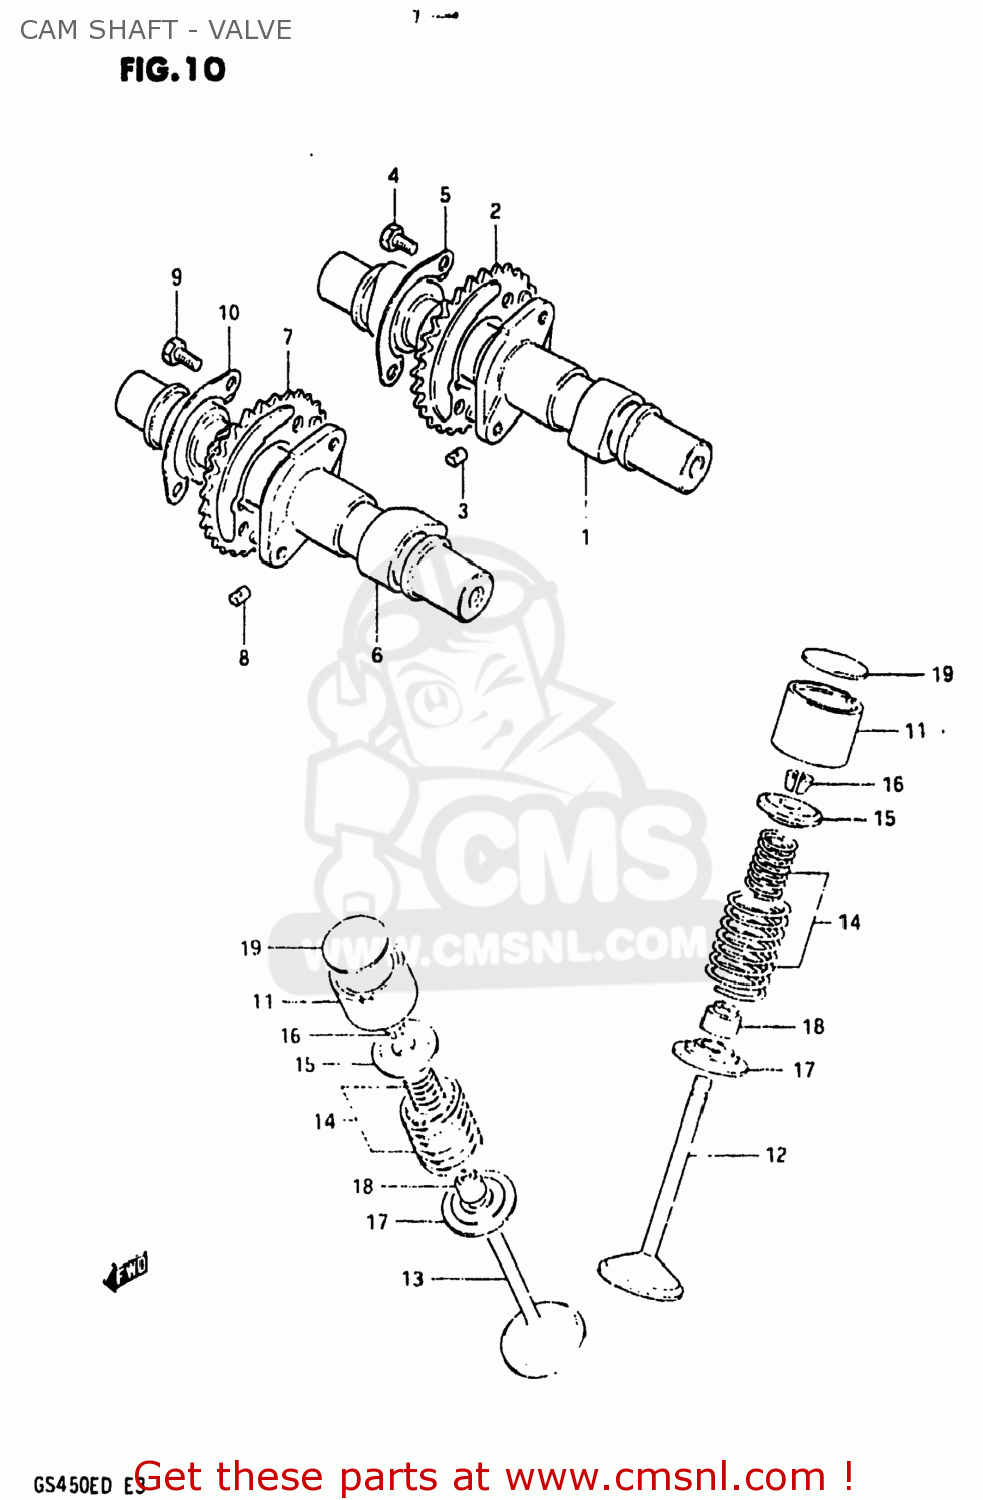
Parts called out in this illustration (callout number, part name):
1	CAMSHAFT,INTAKE
2	SPROCKET,CAMSHAFT
3	PIN,SPROCKET
4	BOLT(6X12.5)
5	WASHER,CAM CHAIN SPROCKET
6	CAMSHAFT,EXHAUST
7	SPROCKET,EXHAUST CAM(NT:30)
8	PIN,SPROCKET
9	BOLT(6X12.5)
10	WASHER,CAM CHAIN SPROCKET
11	TAPPET
12	VALVE,INTAKE
13	VALVE,EXHAUST
14	SPRING SET,VALVE
15	RETAINER,VALVE SPRING
16	COTTER VALVE
17	SEAT,VALVE SPRING
18	SEAL,OIL(7X14.4X9)
19	SHIM,TAPPET
20	SHIM SET,TAPPET
21	CASE
